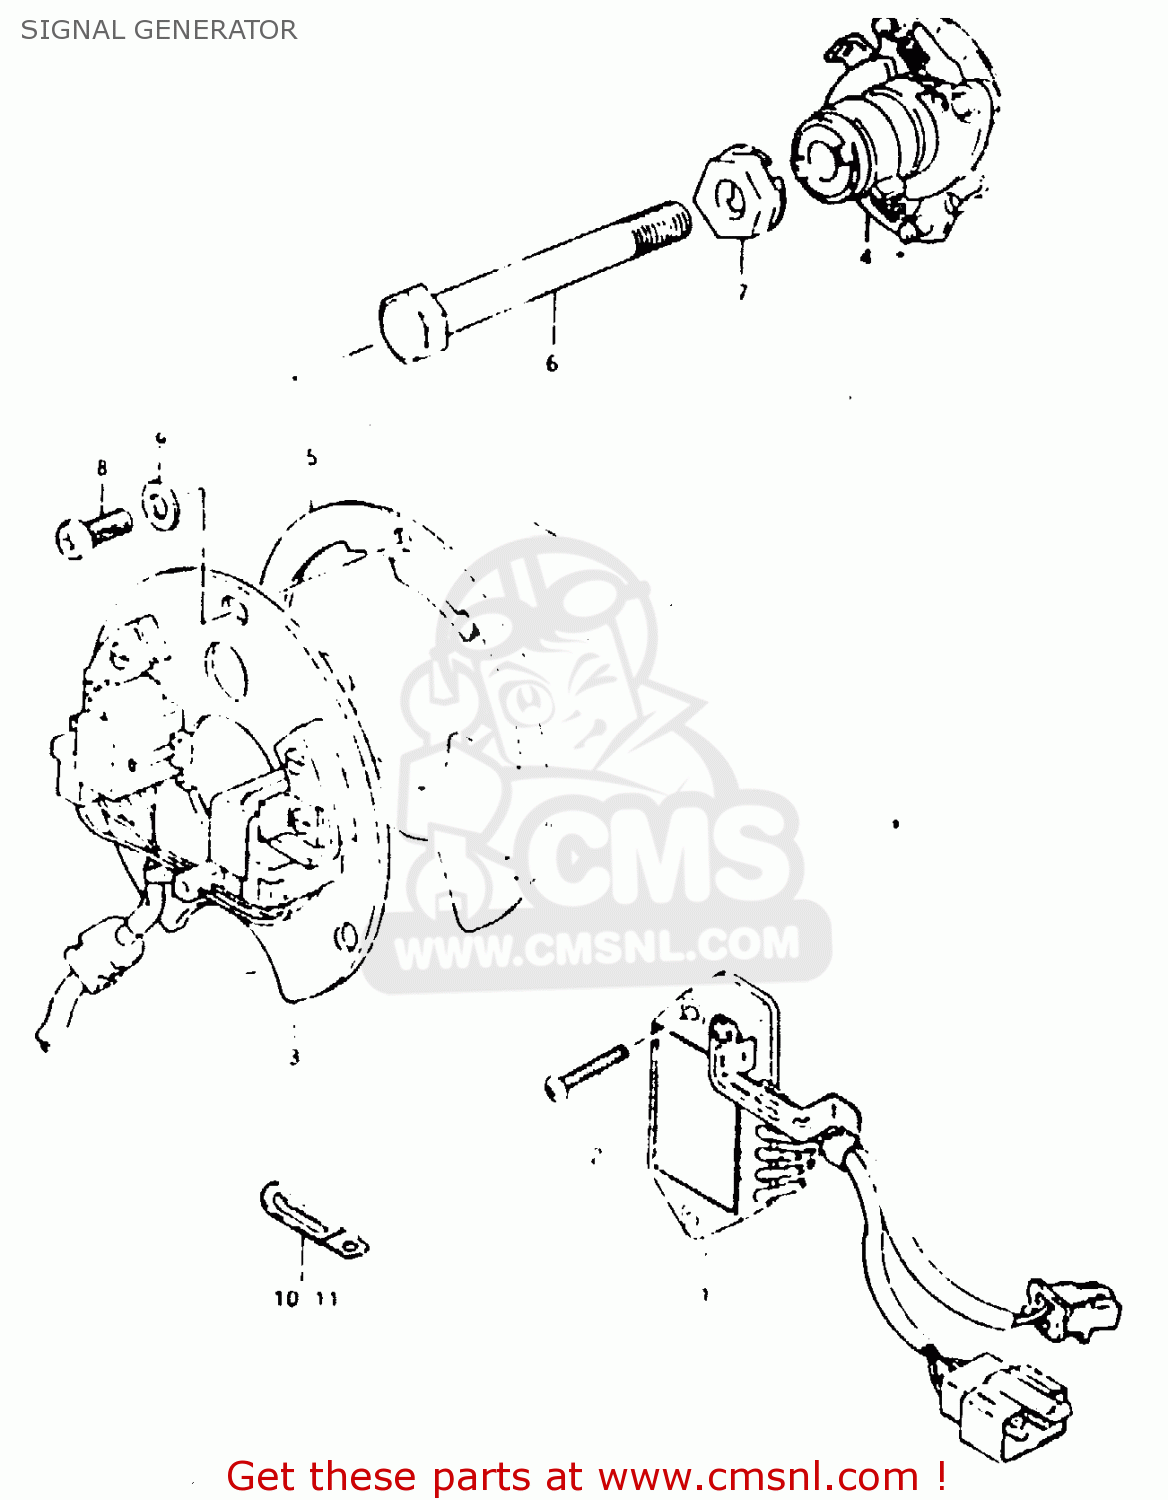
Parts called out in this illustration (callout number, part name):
1	IGNITER UNIT
2	SCREW
3	SIGNAL GENERATOR ASSEMBLY
4	GOVERNOR ASSEMBLY
5	PLATE,TIMING
6	BOLT
7	WASHER
8	SCREW(5X12)
9	WASHER
10	CLAMP L:35
11	CLAMP
